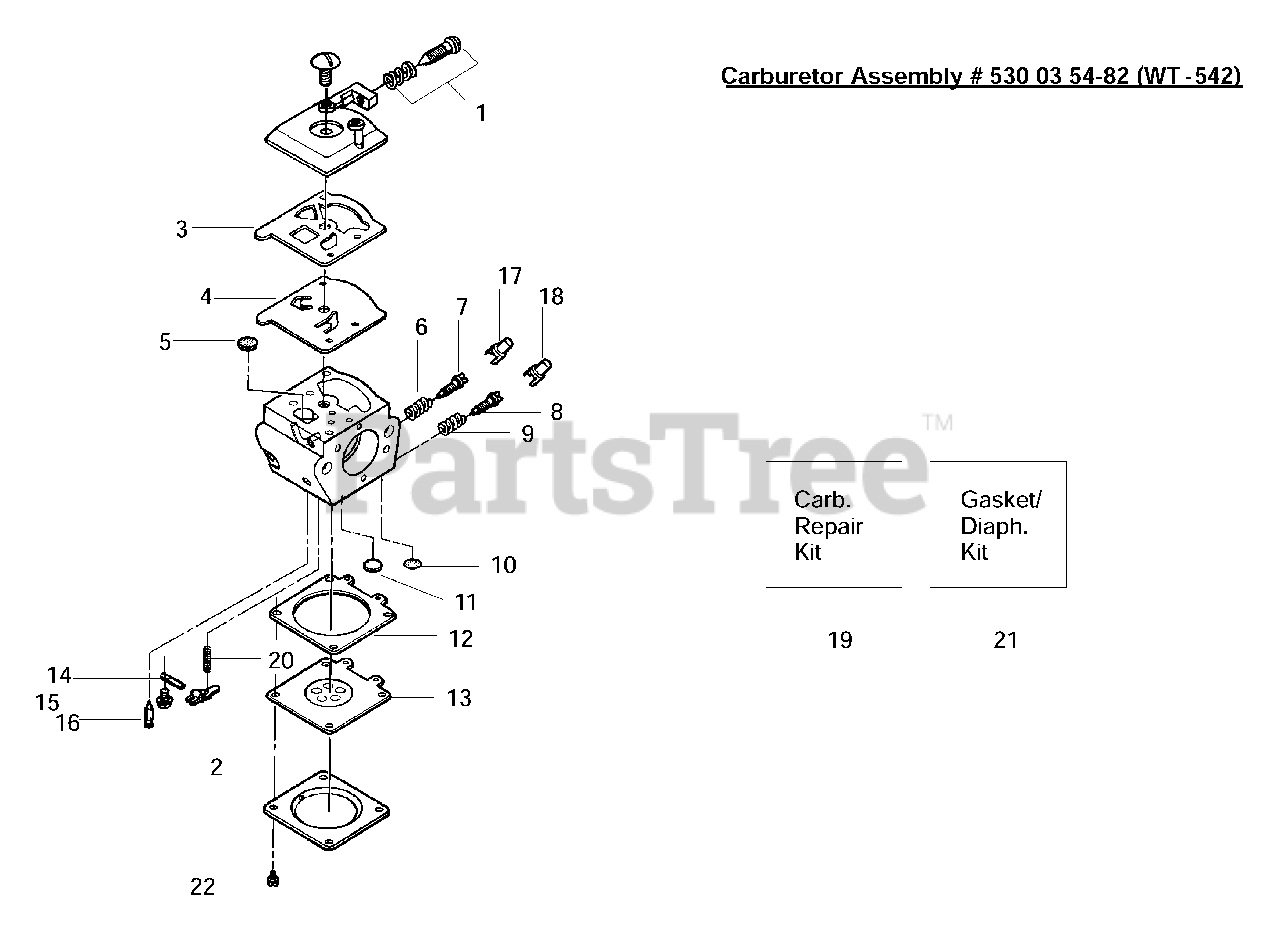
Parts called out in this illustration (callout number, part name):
1	Idle Adv. Screw Kit
2	Metering Lever
3	Fuel Pump Gasket
4	Fuel Pump Diaphragm
5	Fuel Inlet Screen
6	Needle Spring (Low Speed)
7	Low Speed Needle
8	High Speed Needle
9	Needle Spring (High Speed)
10	Welch Plug (5/16)
12	Metering Diaphragm Gasket
13	Metering Diaphragm
14	Metering Lever Pin
15	Metering Lever Pin Screw
16	Inlet Needle Valve
17	Limiter Cap High
18	Limiter Cap Low
19	Carburetor Repair Kit Walbro
19	Carburetor Repair Kit Zama
20	Metering Lever Spring
21	Gasket/Diaphragm Kit Walbro
21	Gasket/Diaphragm Kit Zama
22	Metering Cover Screw Ass'y
530035482	Carburetor Assembly (WT - 542)
